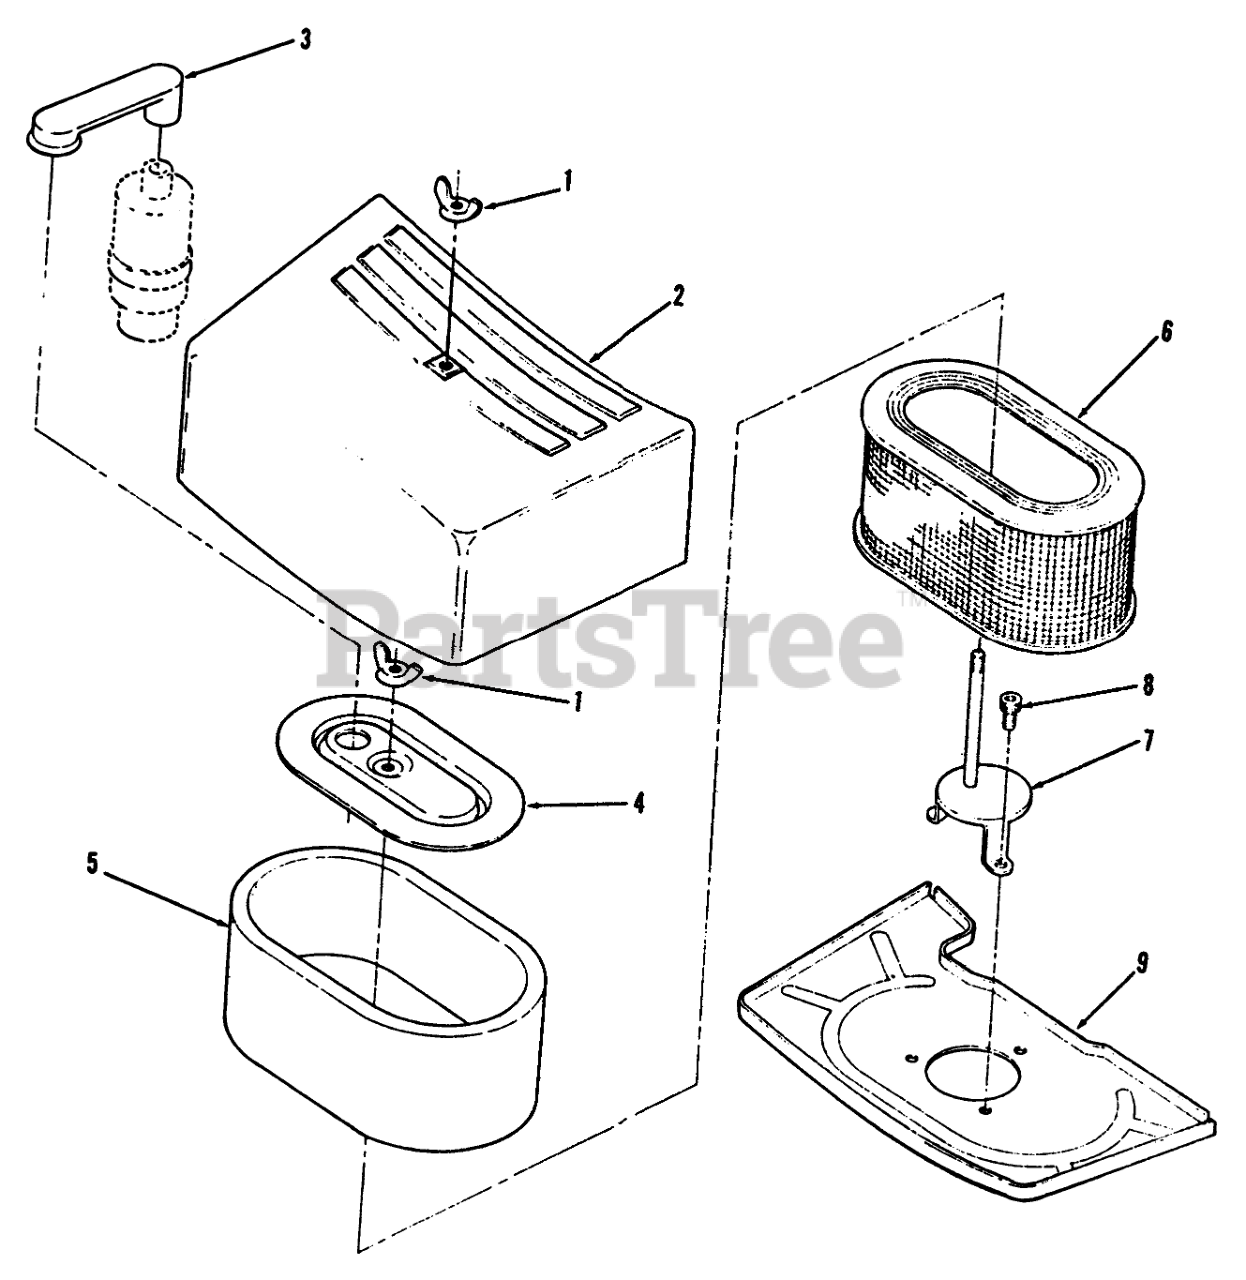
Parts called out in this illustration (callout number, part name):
1	Nut-Wing
2	Hood
3	BREATHER-TUBE
4	ELEMENT-COVER (ZINC)
5	ELEMENT-WRAPPER
6	Support
7	HOOD-SUPPORT
8	SOCKET-HEAD CAP SCRW
9	PAN (ZINC)
